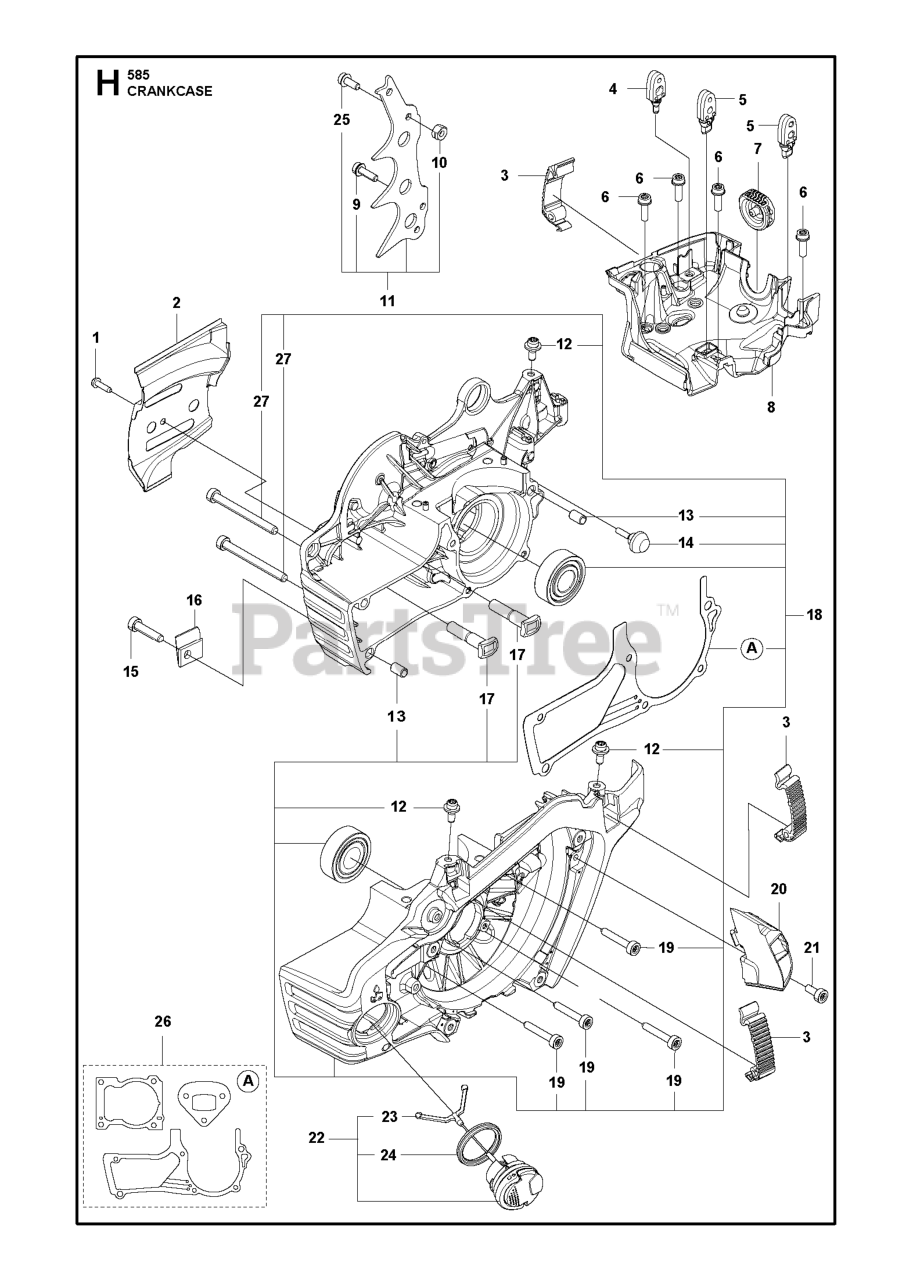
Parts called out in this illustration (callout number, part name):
2	CHAIN GUIDE PLATE BAR MOUNT
3	SNAP LOCKING GREY. ONLY USE F
5	DAMPER INLET SYSTEM
7	GROMMET THROTTLE WIRE
8	CARBURETTOR AREA BASE ASSY
9	SCREW
11	SPIKE KIT INNER NON - WRAP H58
12	SCREW ITXSCM WASHER M5X12 T27
13	GUIDE BUSHING
16	CHAIN CATCHER
18	CRANKCASE KIT 90CC SPARE PARTS
20	AIR NOZZLE
21	SCREW ITXSCM
22	TANK CAP ASSY
26	GASKET KIT 90 CC SPARE PART
